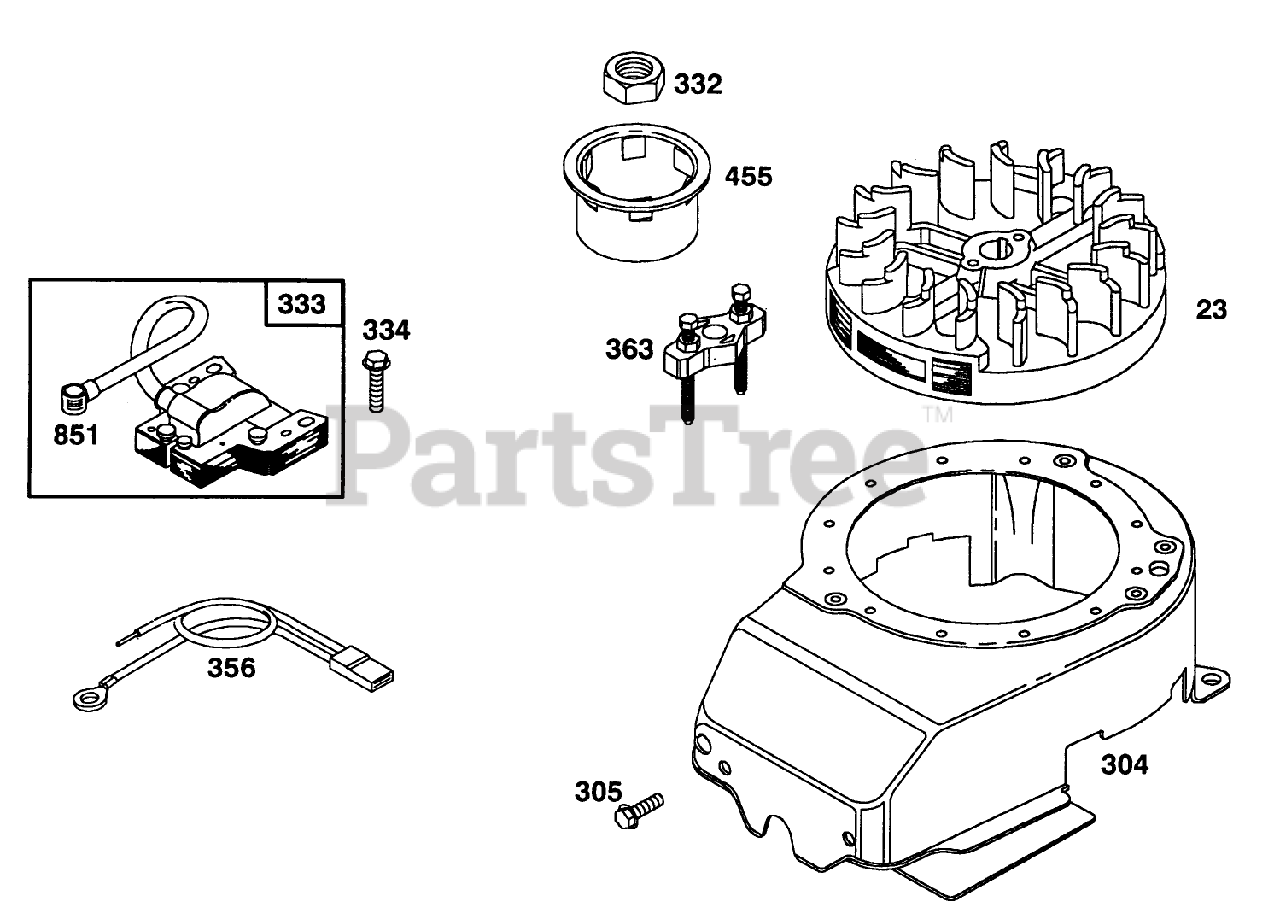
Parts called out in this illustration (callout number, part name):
23	Flywheel
304	Housing-Blower
305	Screw-Sem
333	Armature-Magneto
334	Screw
356	Wire Stop
363	Puller-Flywheel
455	Cup-Starter
851	Terminal-Cable
